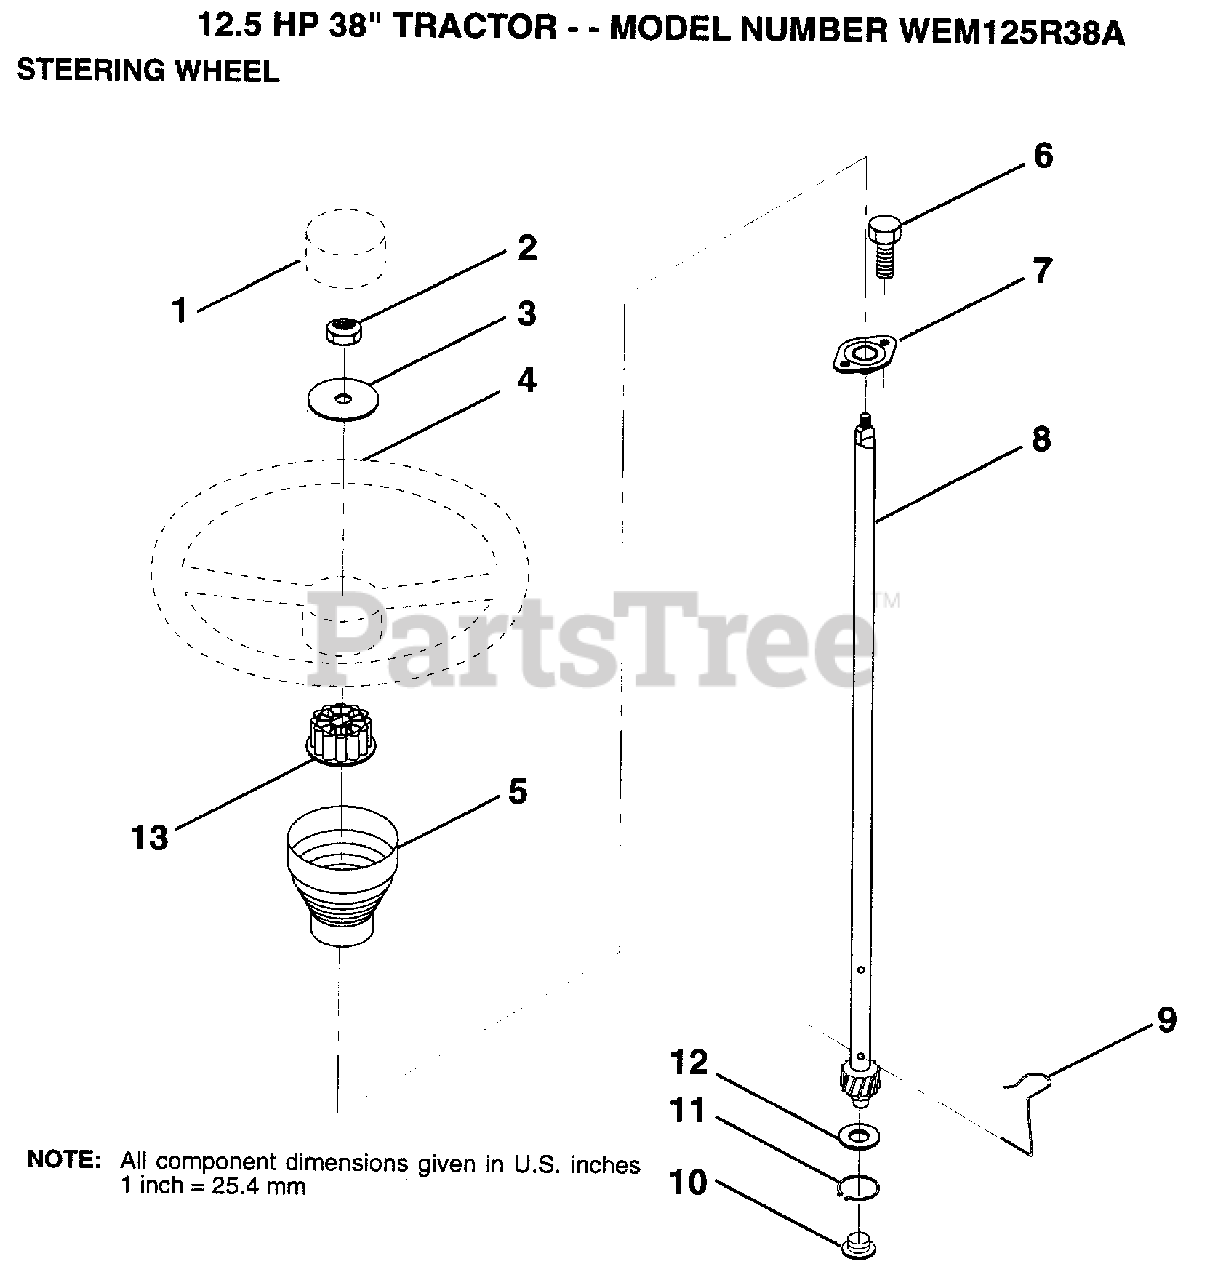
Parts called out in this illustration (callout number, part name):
1	ST WHL INSERT CAP
2	GRIPCO NUT
3	WASHER T
5	SLEEVE STEERING
9	STEERING CLIP
10	BUSHING STEER LWR
11	RING
12	WASHER LT
13	ADAPTER-WHEEL LT
